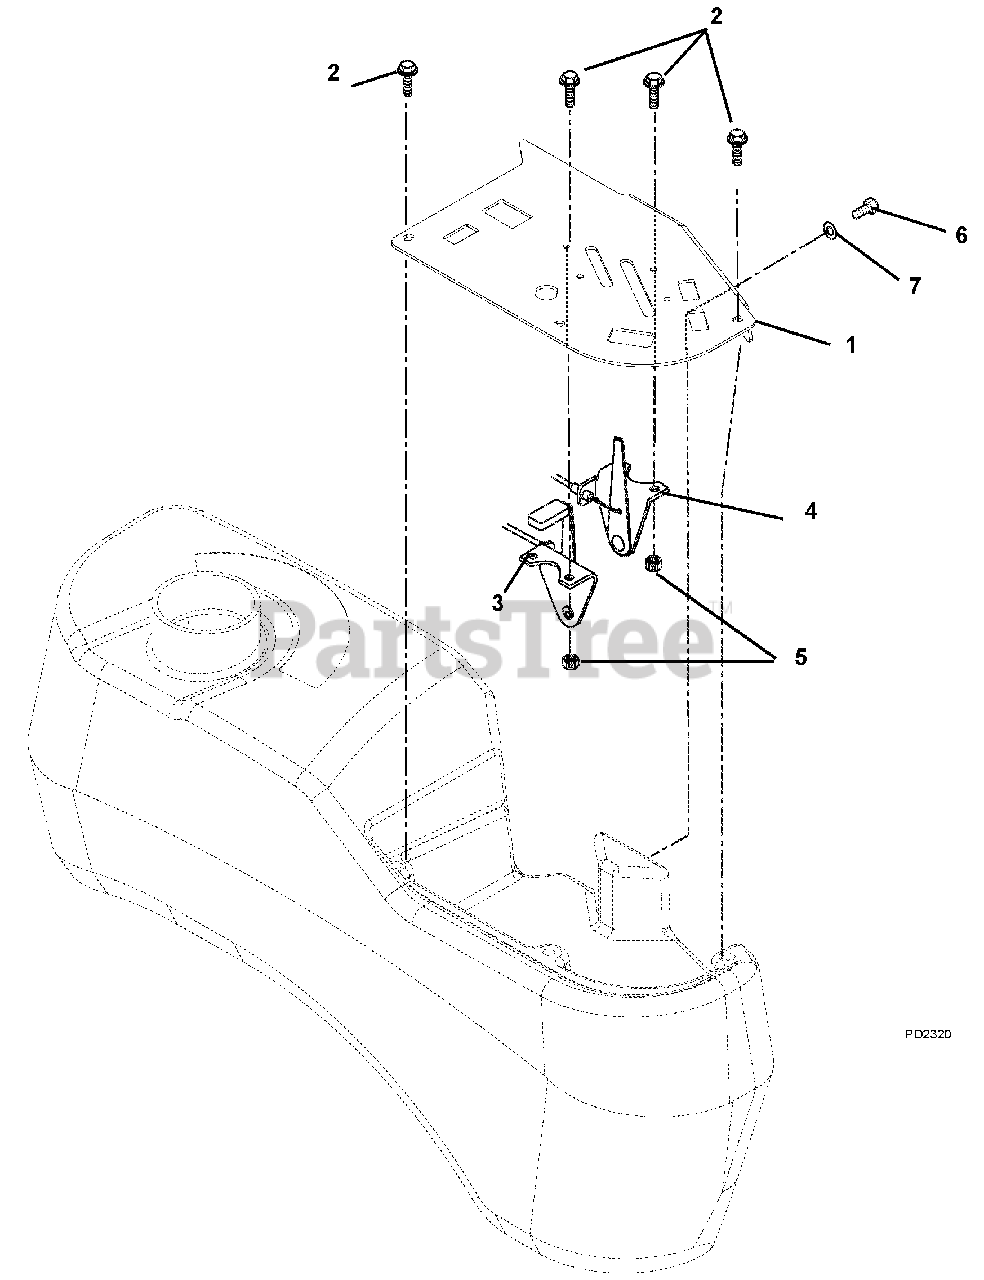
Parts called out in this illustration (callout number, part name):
1	Panel, Control
2	Screw, Machine 10-24 x .50 Hex Washer Head, Stainless
3	Throttle, Control
4	Choke Control
5	Nut, Locking Nylon 10-24 With Insert
6	Bolt-Hex .31-18 x .75 Grade 5
7	Washer-Flat-Steel .38 x .875 x .083
